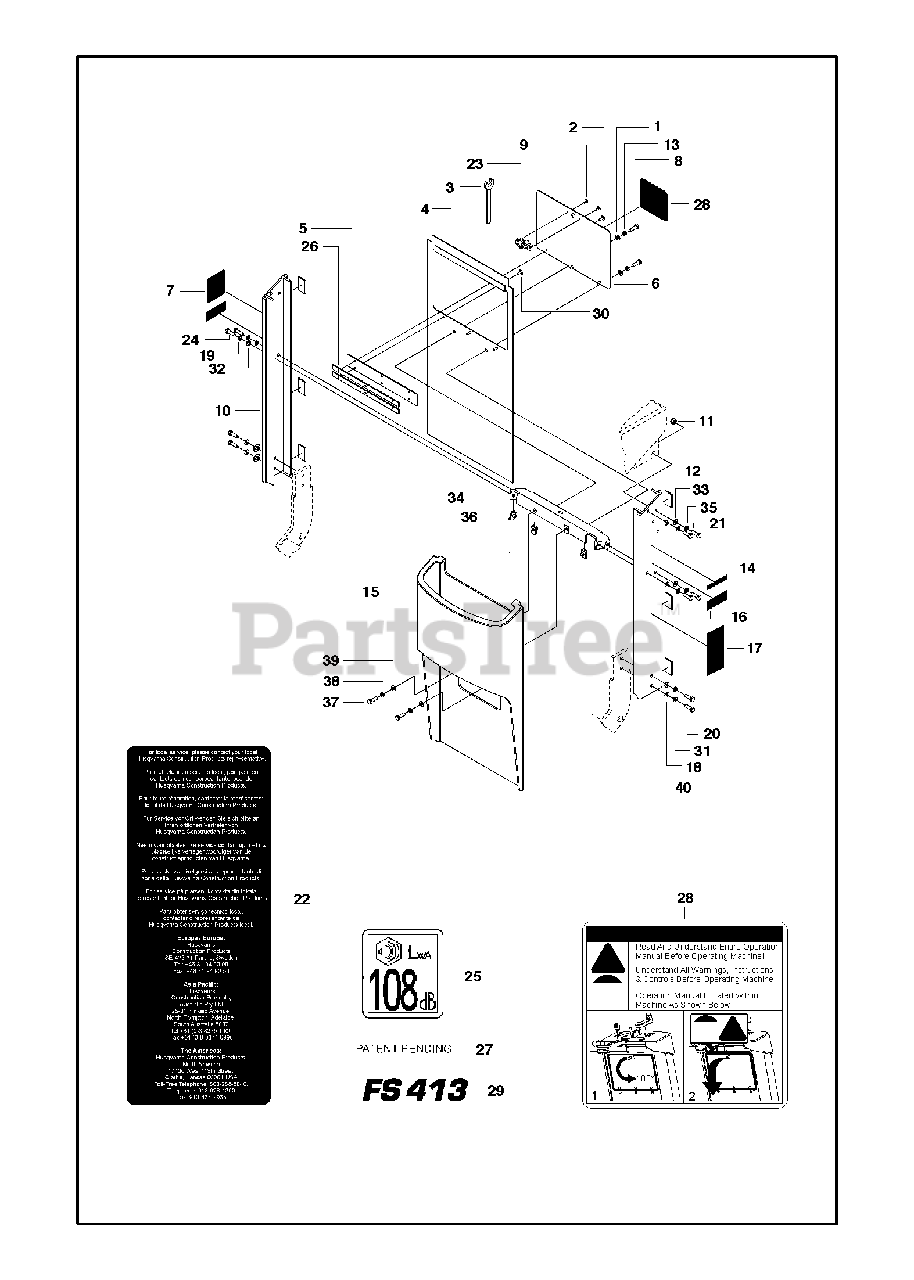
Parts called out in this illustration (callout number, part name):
1	WASHER
11	HEXAGON LOCKING NUT
13	SPRING WASHER
18	WASHER
19	SPRING WASHER
31	SPRING WASHER
32	WASHER
33	WASHER
35	SPRING WASHER
38	SPRING WASHER
39	WASHER
